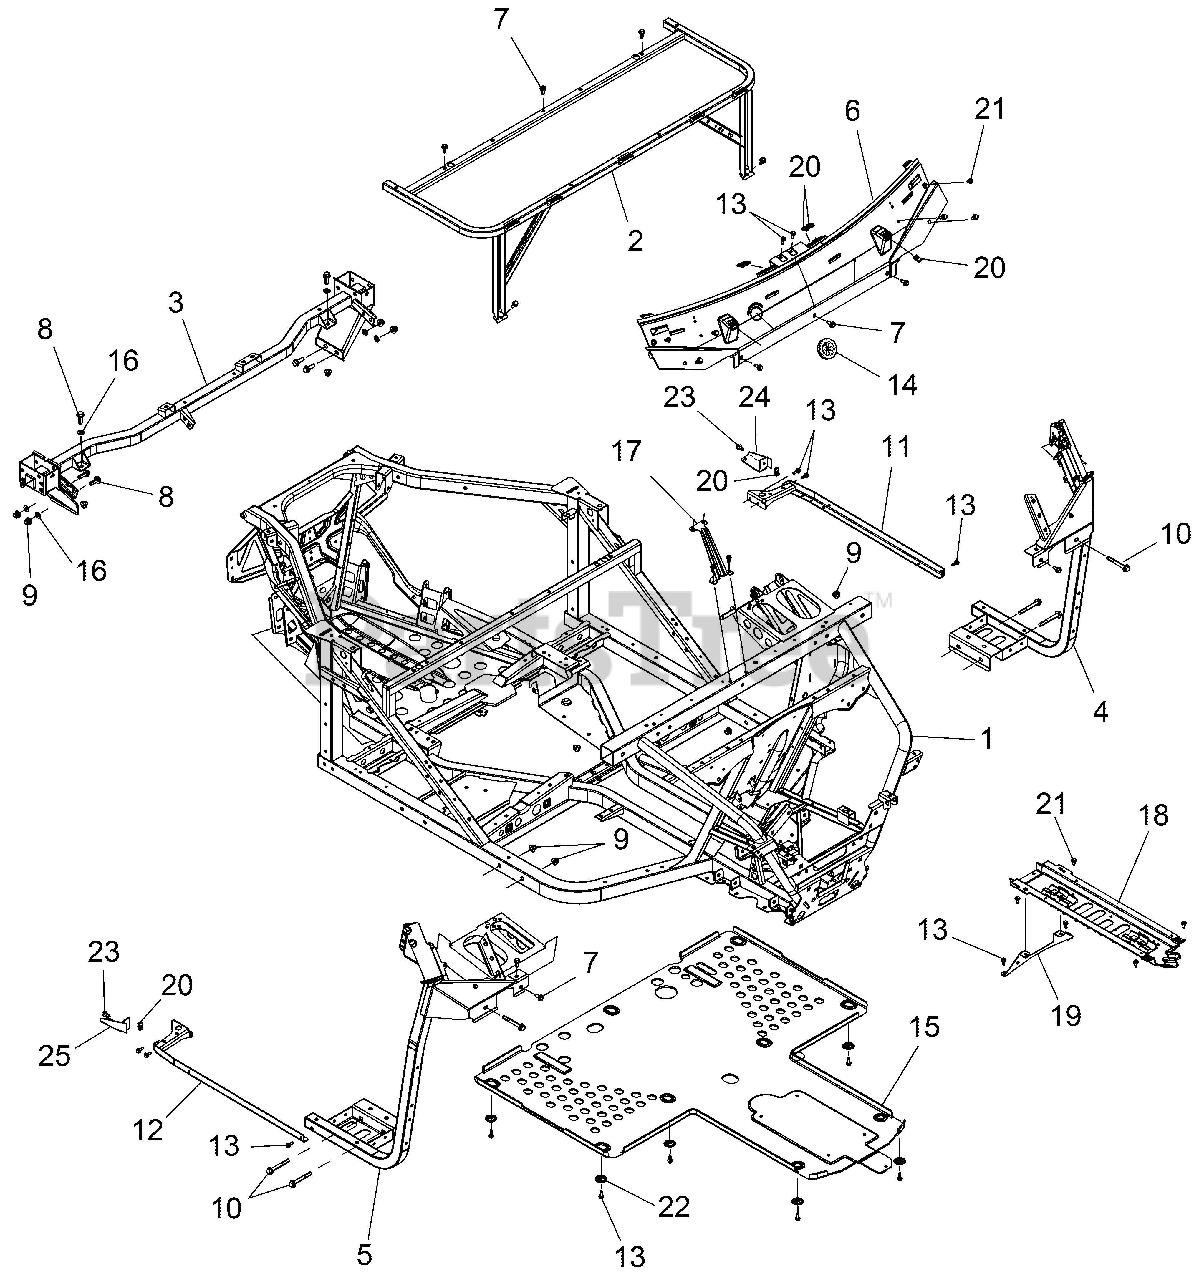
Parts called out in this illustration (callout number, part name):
1	WELD-FRAME,MAIN,ARNS,DSL,BLK
2	WELD-CAB/SEAT BASE,BLK
3	WELD-CAB SUPPORT,REAR,BLK
4	WELD-FLOOR SUPPORT,LH,BLK
5	WELD-FLOOR SUPPORT,RH,BLK
6	PLATE,WINDSHIELD MOUNT,LOW BLK
7	BOLT-M8X1.25X20,HXFLG,TAP/R-OD
8	SCR-HXFL-M10X1.25X30 8.8 ZOD
9	NUT-M10X1.25,FLG,NYLOC-OLIVE D
10	SCR-HXFL-M10X1.25X80 8.8 ZOD
11	WELD-ROCKER,LH,BLK
12	WELD-ROCKER,RH,BLK
13	SCR-M6X1.0X20,HXHD,FLG,TDFM,BL
14	GROMMET-ELEC,CAB,SLIT
15	PLATE-SKID,BLK
16	WASHER,3/8 FW
17	BRKT-PLATE,CTR,PIN MT,TTN
18	TRAY-ROUTING,BLK
19	BRKT-ROUTING TRAY,BLK
20	CLIP-U SPEED NUT
21	RIVET-TUFLOK,.315-.325X.787 (5
22	WASHER SKID PLATE
23	SCR-TXTH-M6X1.0X25 RIE
24	BRACKET,SUPPORT,ROCKER,LH
25	BRACKET,SUPPORT,ROCKER,RH
